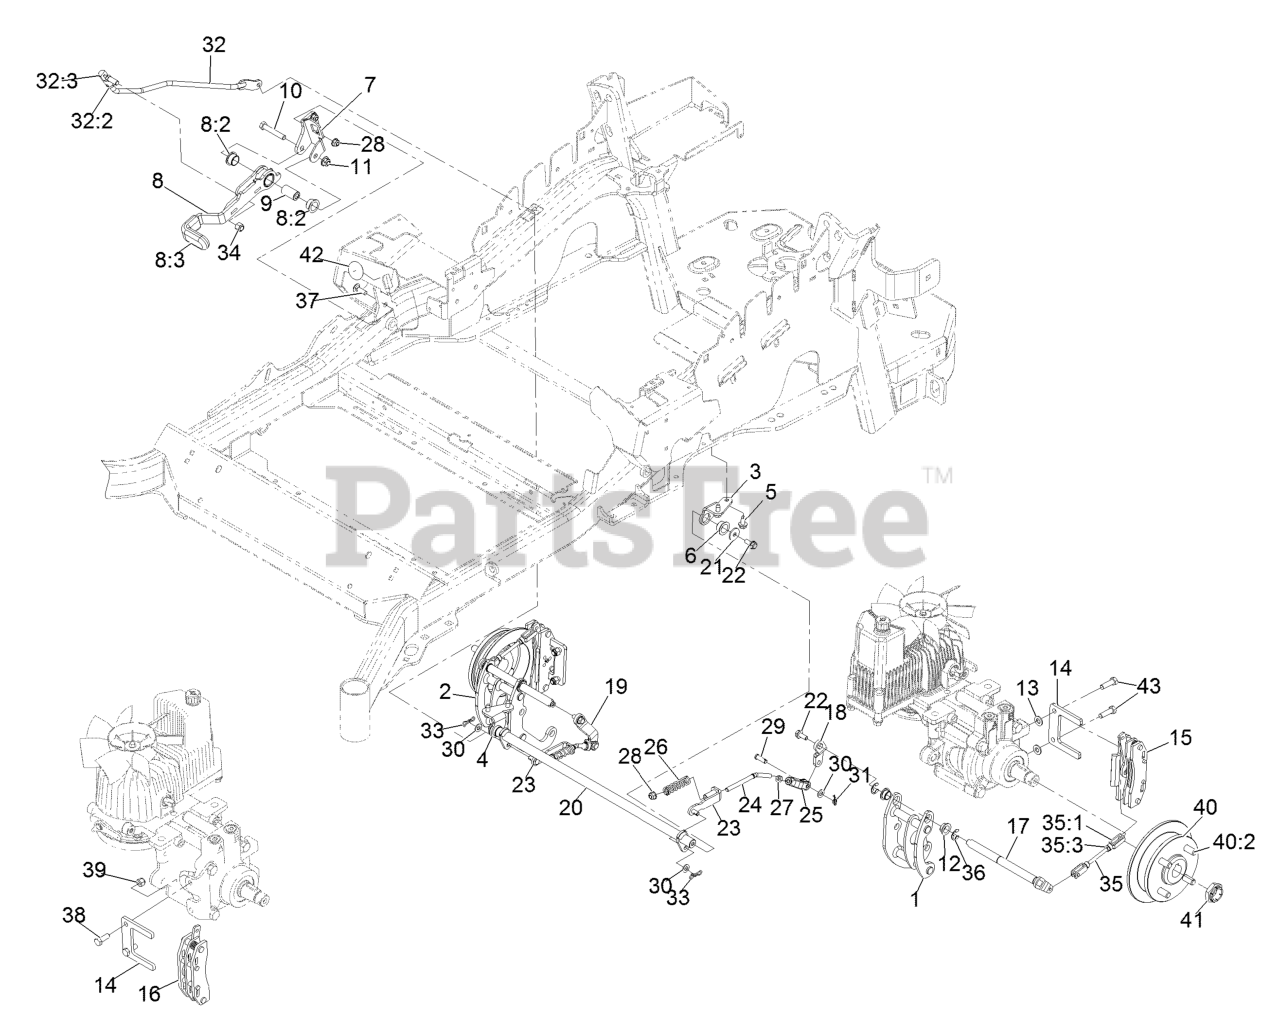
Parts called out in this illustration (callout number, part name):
3	MOUNT-PIVOT, LH
4	MOUNT-PIVOT, RH
5	Screw-HWH 5/16-18 X 3/4 Tf
6	BUSHING-FLANGE
7	BRACKET-MOUNT
8	BRAKE LEVER ASM
8:2	BUSHING-FLANGE
8:3	GRIP-LEVER
9	HANDLE-PIVOT, BRAKE
10	SCREW-HH
11	NUT-HF, NI
12	BUSHING
13	WASHER-FLAT
14	PLATE-MOUNT, BRAKE
15	CALIPER-BRAKE
16	CALIPER-BRAKE, RH
18	ARM-INNER, LH
19	ARM-INNER, RH
20	SHAFT-CROSS
21	WASHER-FLAT
22	SCREW-HHF
23	BRACKET-L
24	LINKAGE-MID
25	YOKE-OFFSET
26	SPRING-COMPRESSION
27	NUT-JAM
28	NUT-HF, NI
29	PIN-CLEVIS
30	WASHER-PLAIN
31	PIN-COTTER, LOCKING
32	FRONT LINKAGE ASM
32:2	END-TIE ROD, RH
32:3	NUT-HJ
33	PIN-COTTER, LOCKING
34	NUT-LOCK
35	REAR LINKAGE ASM
35:3	NUT-JAM
37	BOLT-CARR
38	SCREW-HH
39	NUT-LOCK, NI
40	WHEEL HUB ASM
40:2	STUD-WHEEL
41	LOCKNUT
42	DECAL-COVER
43	SCREW-LOCK, PATCH
